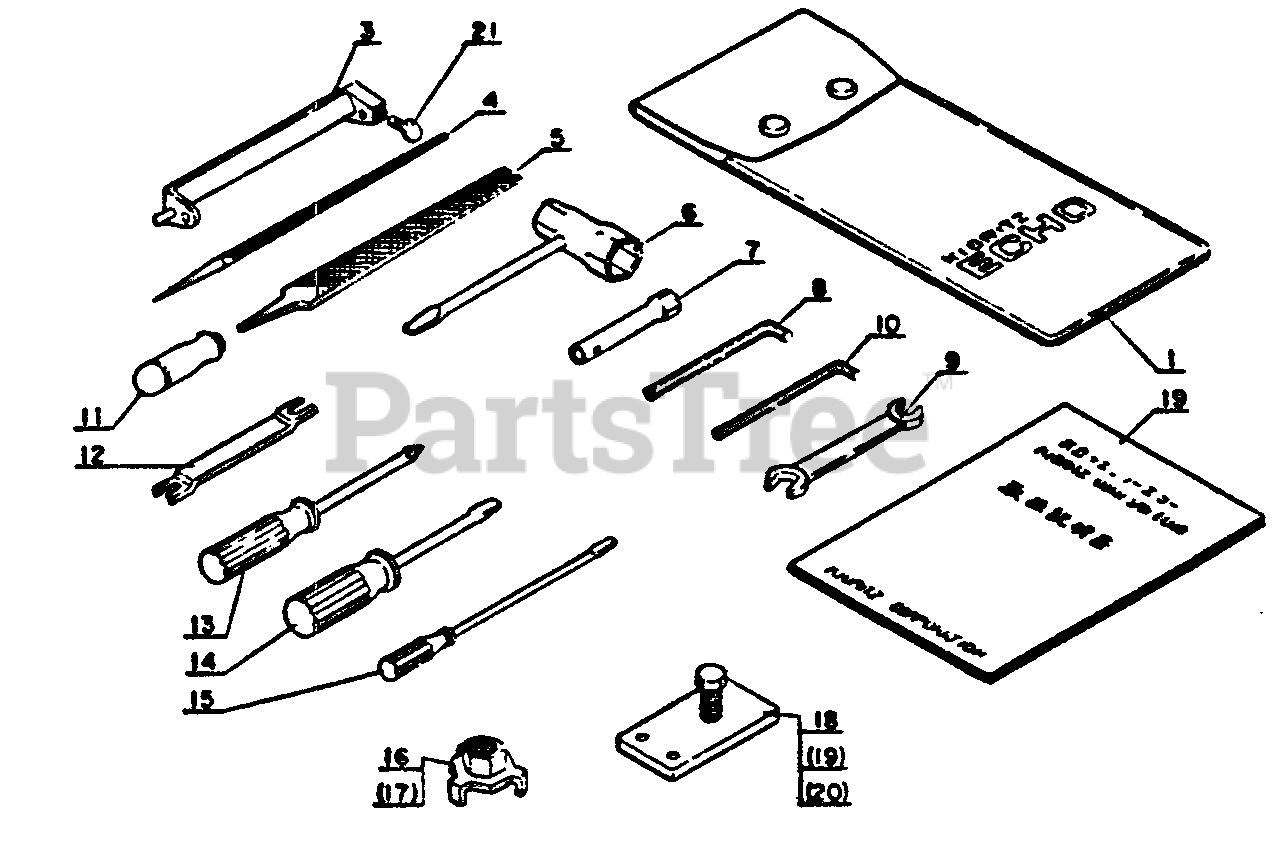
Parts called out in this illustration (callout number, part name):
1	BAG, TOOL
3	FILE HOLDER
4	ROUND FILE
5	FLAT FILE
6	BOX WRENCH, W/DRIVER - 19×13
7	BOX SPANNER - 8
8	WRENCH, ALLEN 4 MM
9	SPANNER 7×8
10	WRENCH, ALLEN 3 MM
11	FILE GRIP
12	GAUGE, DEPTH
13	SCREWDRIVER - CROSS HEAD
14	SCREWDRIVER - 75 MM
15	SCREWDRIVER, SLOTTED
16	PULLER (CLUTCH)
18	PULLER (MAGNETO)
19	OWNER'S MANUAL
